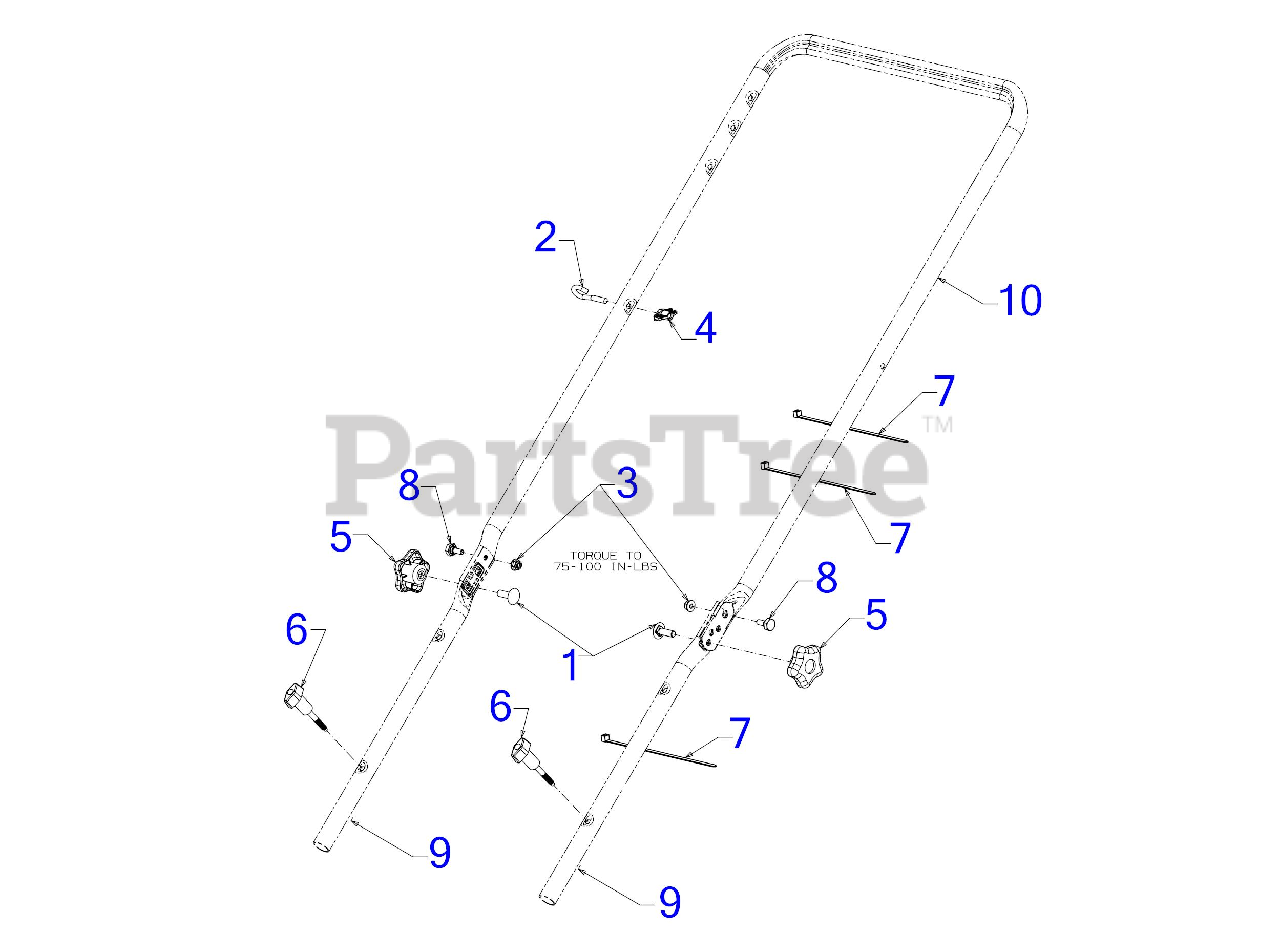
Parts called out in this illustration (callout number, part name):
1	SCREW 5/16-18 x 1.00 GR5
2	EYEBOLT 1/4-20
3	FLANGE LOCK NUT
4	HANDLE KNOB
5	STAR KNOB 5/16-18
6	WING KNOB 1/4-20
7	7" CABLE TIE
8	SHOULDER SCREW
9	LOWER HANDLE
